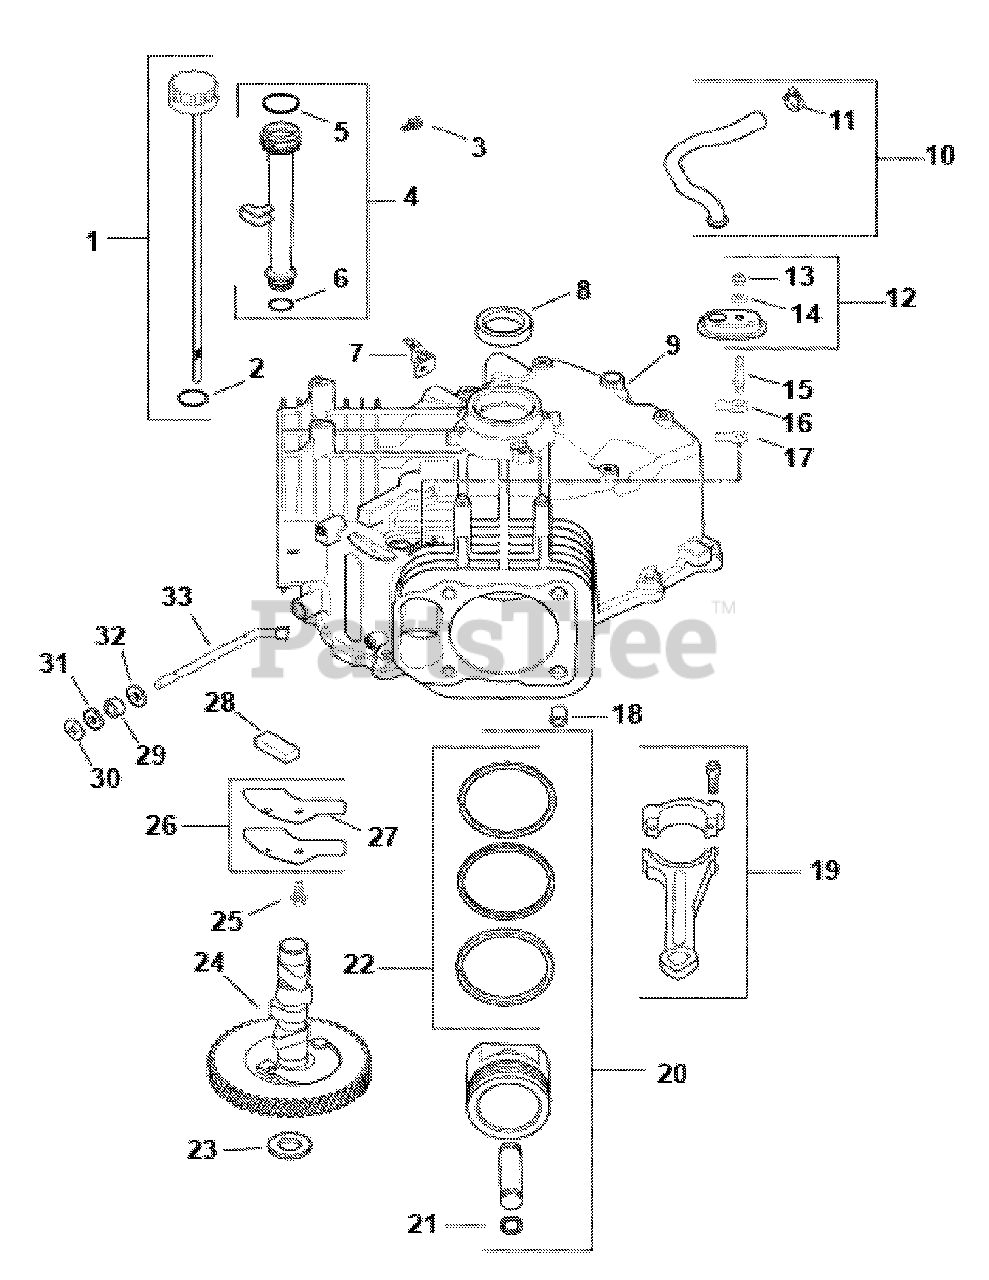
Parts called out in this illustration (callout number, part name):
1	Dipstick Kit
3	Hex Flange Screw
4	Oil Fill Tube
5	Upper Oil Fill Tube O-Ring
6	Lower Oil Fill Tube O-Ring
7	Oil Fill Tube Bracket
8	Oil Seal
9	Use Shortblock
10	Breather Hose / With Clamp
11	Hose Clamp
12	Breather Housing / Washer Nut
14	Sealing Washer
15	Breather Cover Stud
16	Breather Reed Retainer
17	Breather Reed
19	Connecting Rod (Std.)
20	Piston With Ring Set (Std.)
21	Piston Pin Retainer
22	Ring Set (Std.)
23	Camshaft Shim (White)
25	Hex Flange Screw
26	Breather Cover
27	Breather Cover Gasket
28	Breather Filter
29	Governor Cross Shaft Seal
30	Retainer Ring
31	Plain Washer 8 mm
32	Flat Washer 1/4"
33	Governor Cross Shaft
